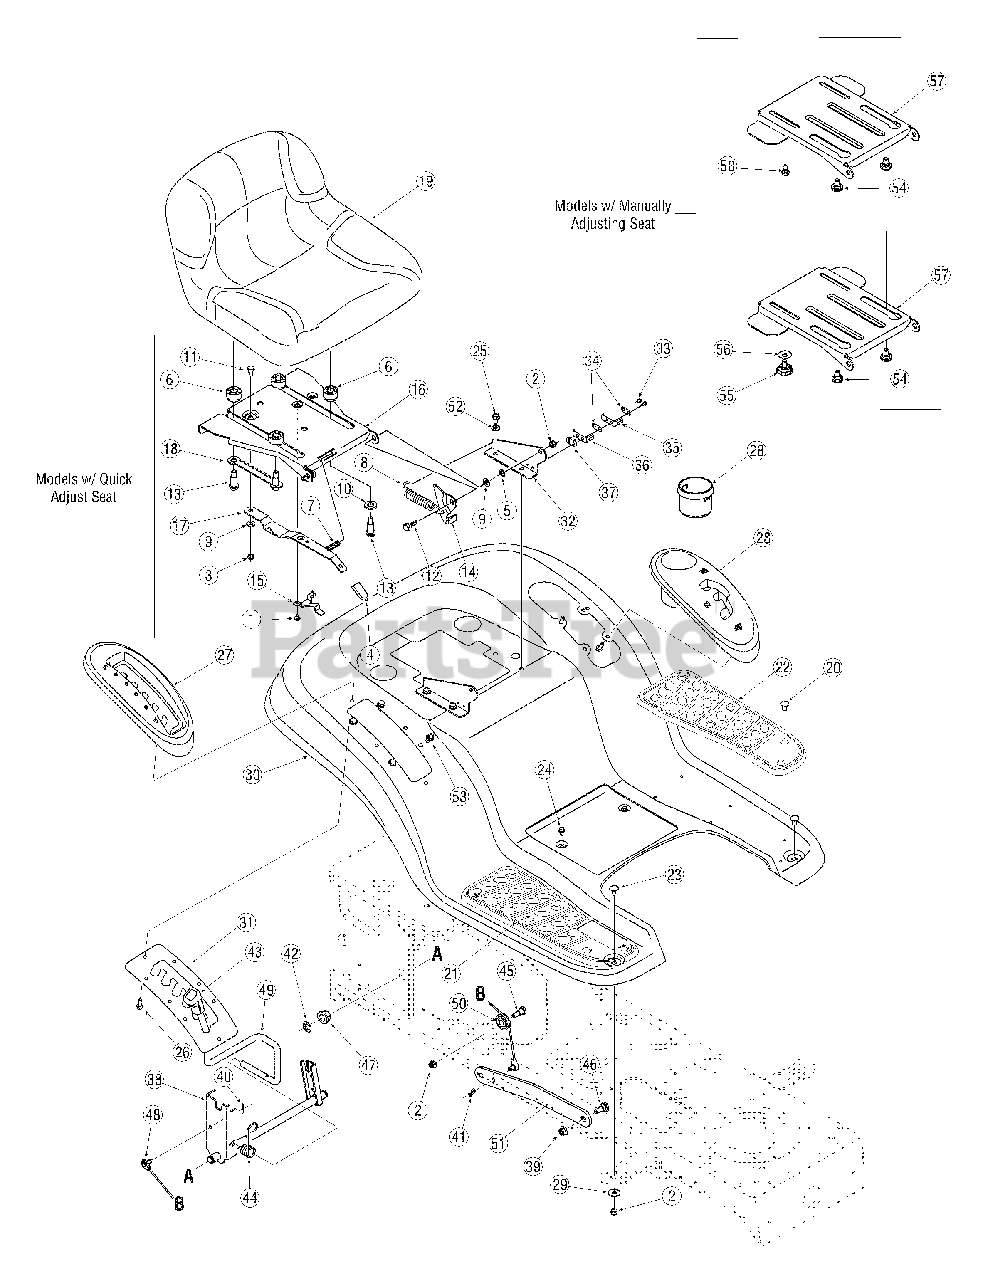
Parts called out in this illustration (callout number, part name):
1	Screw, #10-16 x.375
2	Nut, Flange Lock, 5/16-18, Gr F, Nylon
3	Nut, Flange Lock, 1/4-20
4	Seat Adjuster Grip
5	Nut, Speed,.3125 ID
6	Spacer
7	Compression Spring,.41 x 1.5
8	Spring, Extension,.84 Dia. x 4.6
9	Wash, Flat,.344 x.688 x.065
10	Wash, Flat,.531x 1.062 x.134
11	Screw, Shoulder,.340 x.285,1/4-20
12	Screw, Shoulder,.437 x.268, 5/16-18
13	Screw, Shoulder,.50 x.925, 3/8-16
14	Seat Bracket, Lift (Model 604H/605H)
15	Seat Stop
18	Seat Adjustment Selector
19	Medium Back Seat, Yellow
20	Ratchet Clip
21	RH Foot Pad, Rubber (Model 604H/605H)
22	LH Foot Pad, Rubber (Model 604H/605H)
23	Bolt, Carriage, 5/16-18,.75, Gr1
24	Screw, 1/4-20, 0.500
25	Screw, 5/16-12, 0.750
26	Screw, 1/4-15, 0.750 (Model 604H/605H)
27	Cover, Lift Lever (Model 604H/605H)
28	Cover, w/ Cup Holder (Model 604H/605H)
29	Washer, Flat,.344 x 1.0 x.063
33	Screw, #8-18 x.50
34	Plate, Insulator
35	Spring Switch, Outer
36	Spring Switch, Inner
37	Plate, Insulator Boss
39	Nut, Flange Lock, 3/8-16, Gr F, Nylon
40	Pin, Cotter,.072 Dia. x 1.13
41	Pin, Cotter, 3/32, 1.0
42	Ring, E Type,.625 Dia.
43	Grip, Handle, 1/2
44	Spring, Torsion
45	Screw, 5/16-18 x.620 Gr2
46	Screw, Shldr,.625 x.165, 3/8-16 (42" Deck)
47	Bearing, Hex Flange
48	Cable, Lift, 16.16
49	Handle, Lift
50	Pulley, Roller
52	Lock Washer, 5/16
53	Screw, 5/16-12, 0.750 (Model 604H/605H)
54	Shoulder Screw
55	Knob, 3/8-16
56	Flat Washer,.406 x 1.00 x.030
58	Hex Head Washer Screw, 3/8-16 x.625
